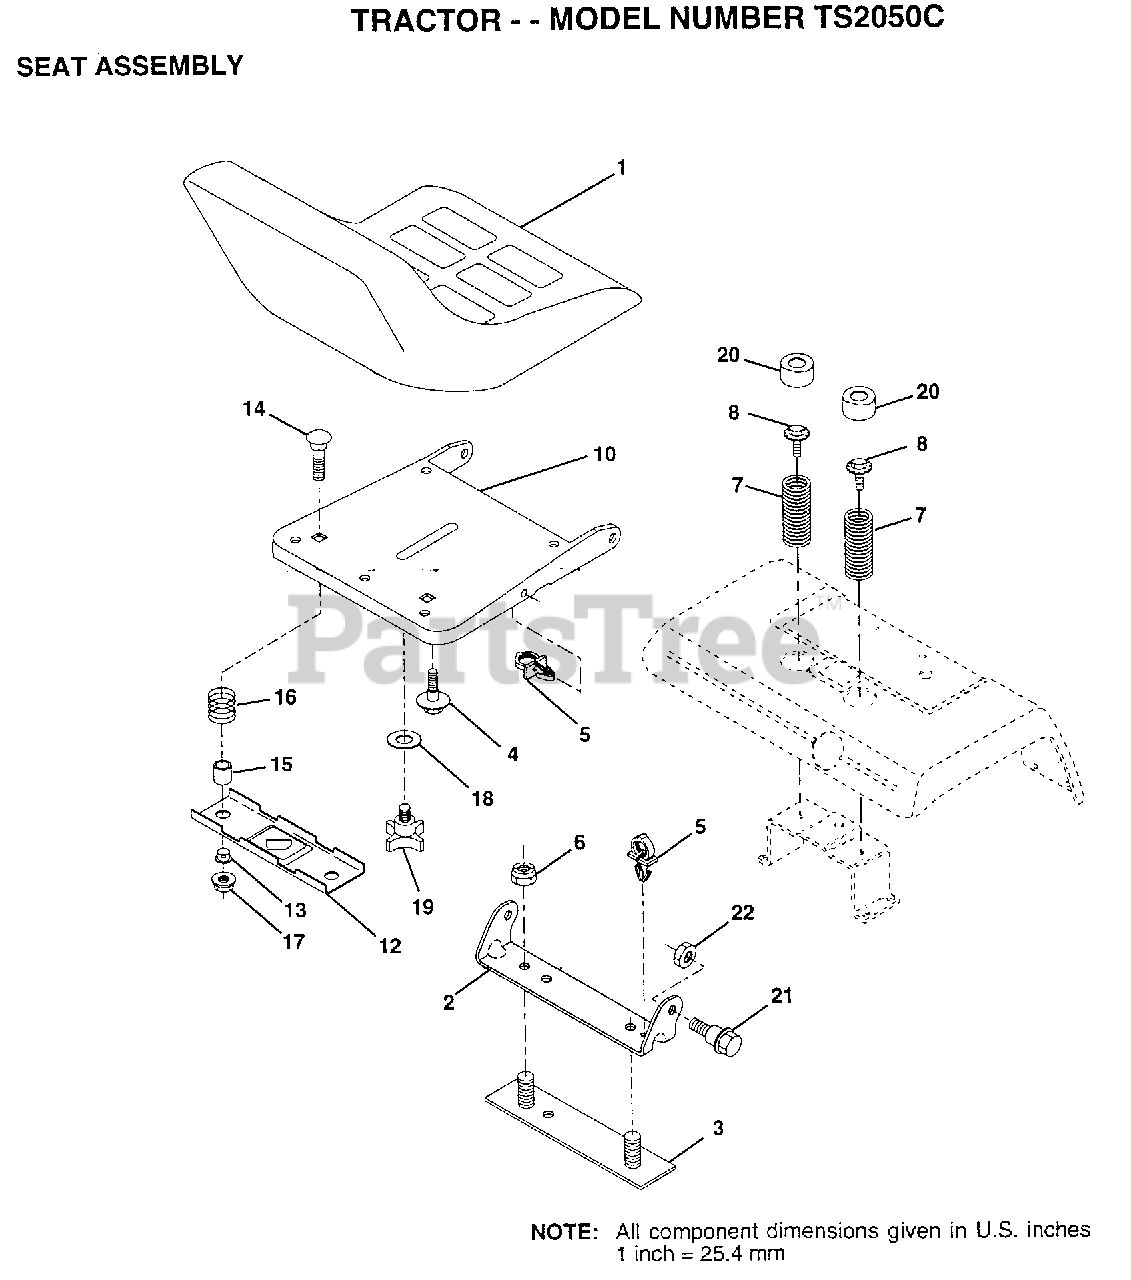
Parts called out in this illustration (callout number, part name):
2	BRACKET PVT SEAT
3	STRAP ASM FENDER
4	"BOLT,SHOULDER"
5	CLIP.PUSH-IN.HING
7	SPRING COMPRESSIO
8	BOLT.5/16-18.UNC
12	BRKT SWITCH
13	BUSHING
15	SPACER SPLIT
16	SPRING COMPRESSED
18	WASHER
19	"KNOB 1/2"" YT"
20	CAP SPRING
21	"BOLT,SHOULDER"
